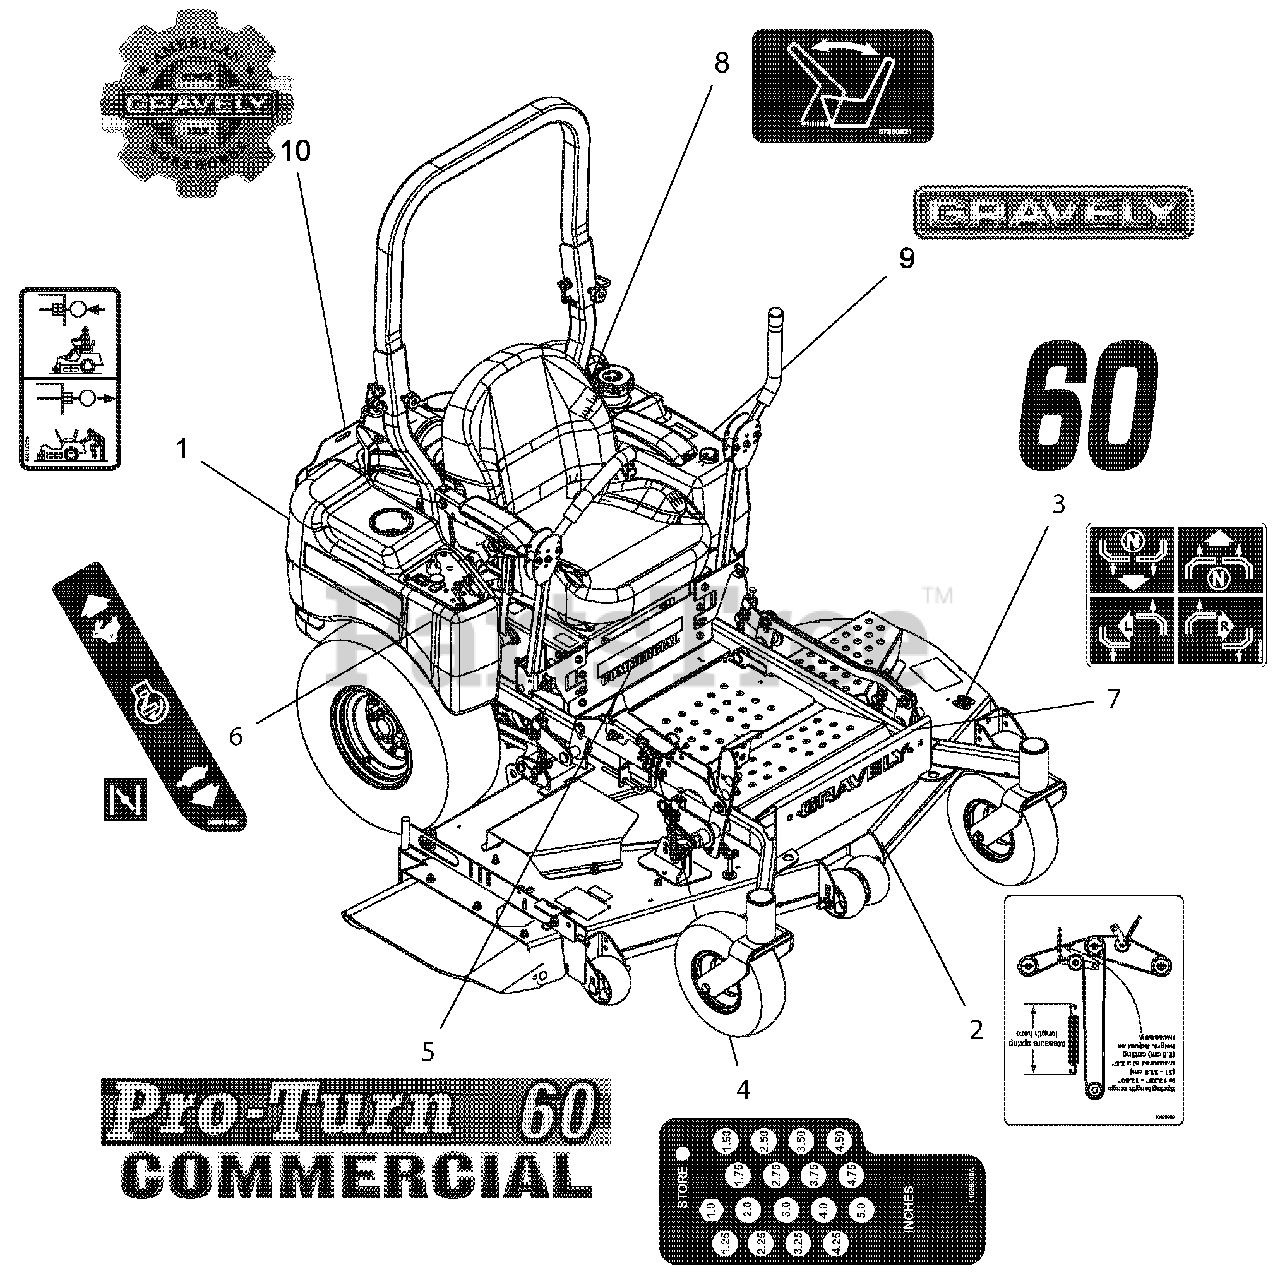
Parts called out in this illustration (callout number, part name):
1	DECAL, TRANSMISSION DISCONNECT
2	DECAL, BELT ROUTING
3	DECAL, 60"
4	DECAL, HEIGHT OF CUT
5	DECAL, 60" PRO-TURN
6	DECAL, SPEED CONTROL
7	DECAL, INSTRUCTIONAL - STEERING
8	DECAL, SEAT RELEASE
9	DECAL, FUEL TANK-GRAVELY
10	DECAL, GRAVELY HERITAGE-LARGE
